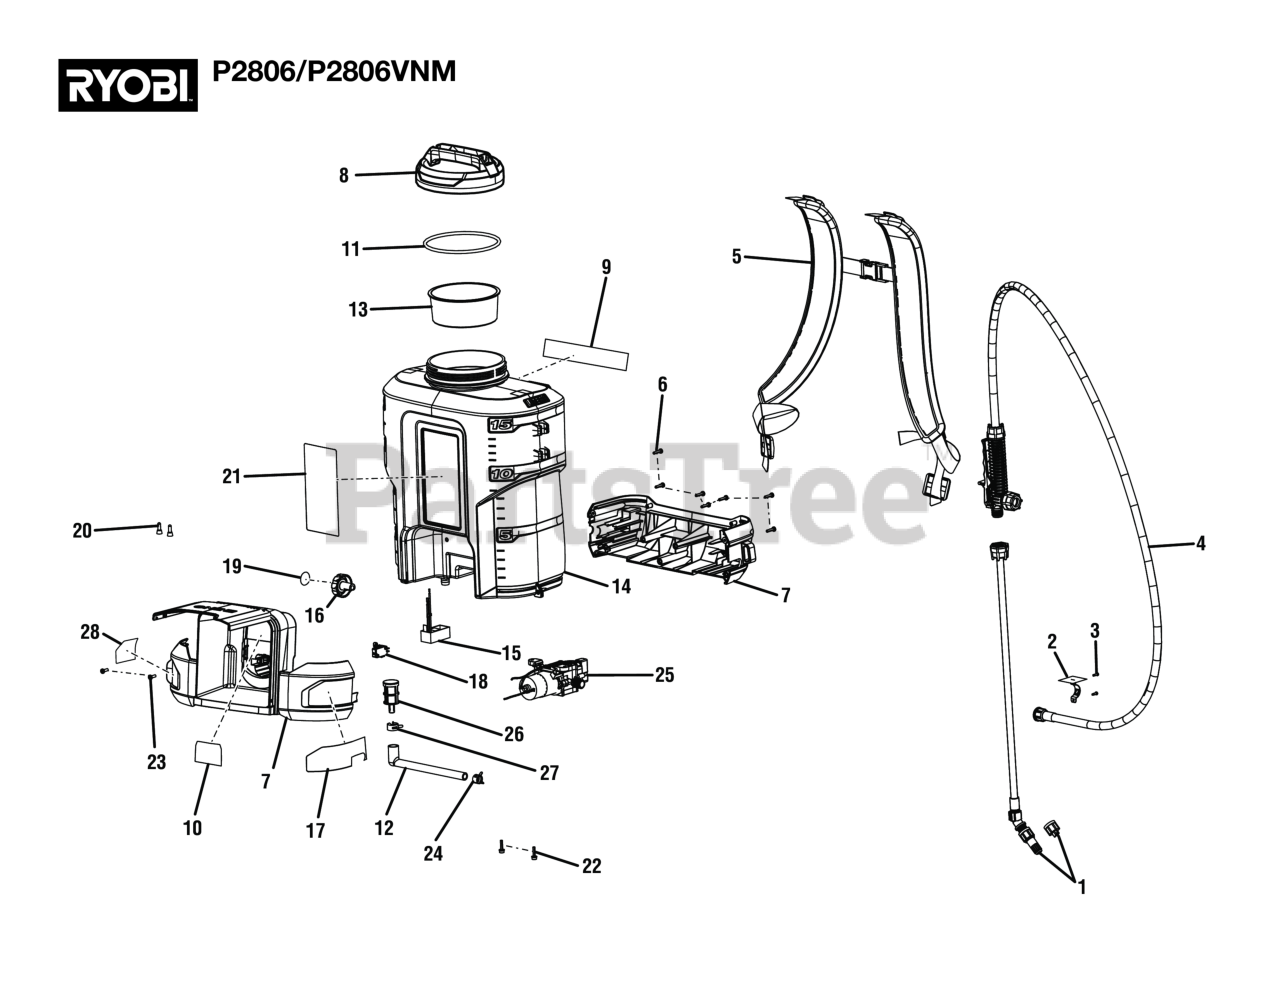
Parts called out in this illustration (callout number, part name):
1	Nozzle and Wand Assembly
3	Screw (M3 x 10 mm, T10 Torx Hd.)
4	Handle and Hose Assembly
6	Screw (M4 x 22 mm Pan Hd.)
7	Housing Assembly
8	Tank Lid Assembly (Inc. Key No. 11)
9	Icon Warning Label
10	Data Label
11	Rubber Gasket
13	Inlet Filter
14	Tank Assembly (Inc. Key Nos. 9 & 21)
15	Flow Rate Control Assembly
16	Adjustable Switch Knob Assembly (Inc. Key No. 19)
17	Warning Label (FR/SP)
18	Micro Switch
19	On\Off Label
20	Wire Connector (Closed End)
21	Logo Label
22	Screw w/Washer (M4 x 19 mm, T20 Torx Pan Hd. S.T.)
23	Screw (M4 x 12 mm)
24	Hose Clamp on Pump
25	Motor and Pump Assembly
26	Filter Assembly
27	Hose Clamp on Tank
28	4 Gal. Callout Label
